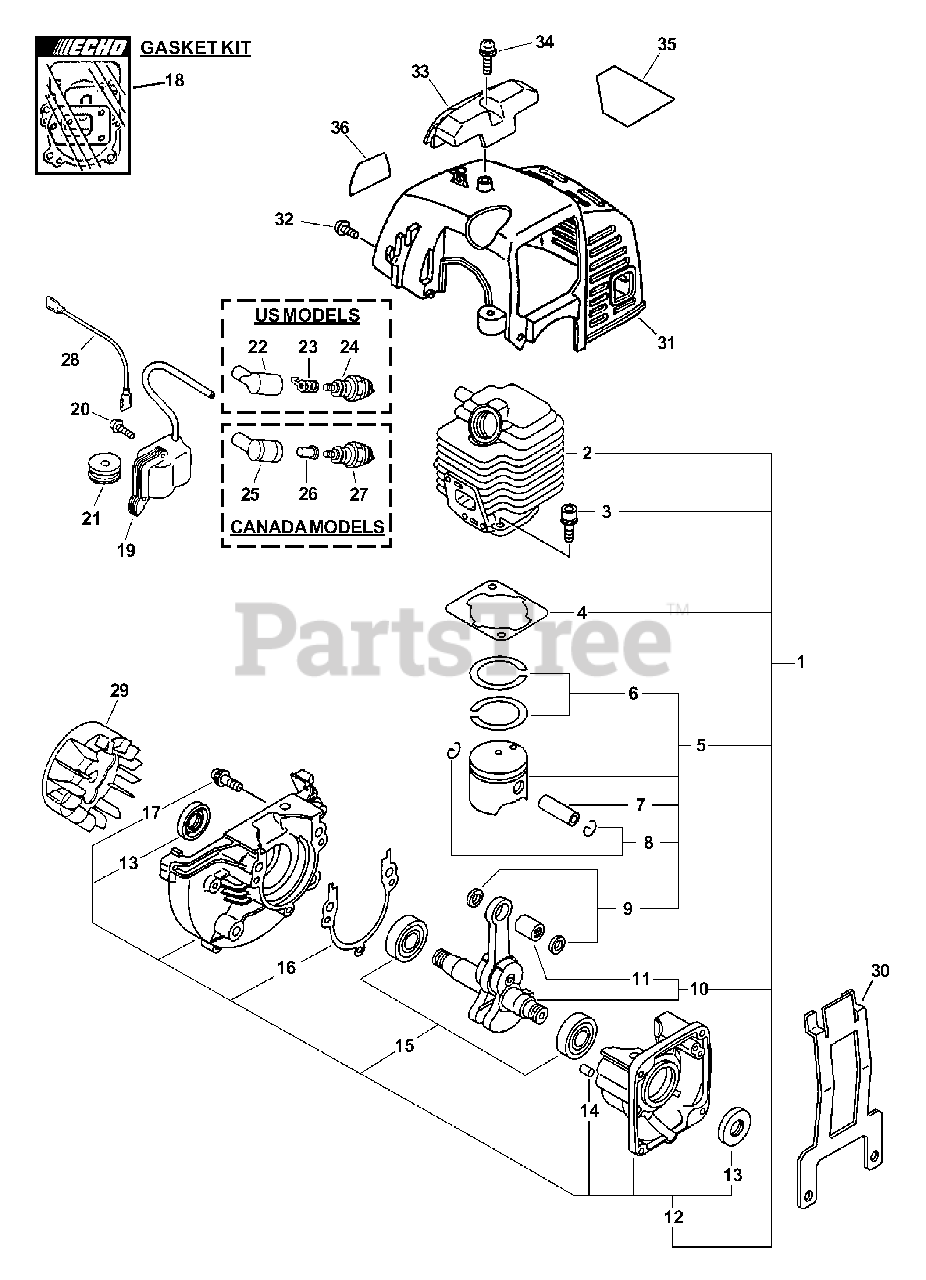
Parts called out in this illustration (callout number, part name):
1	SHORT BLOCK ES-2100;PB-2100
2	CYLINDER
3	BOLT 5×22
4	GASKET, CYLINDER
5	PISTON KIT
6	RING, PISTON
7	PIN, PISTON 8
8	RING, SNAP
9	WASHER, THRUST
10	CRANKSHAFT ASSY
11	BEARING, NEEDLE
12	CRANKCASE KIT
13	SEAL, OIL 12
14	PIN, LOCATING 4
15	BEARING, BALL - 6201 C3
16	GASKET, CRANKCASE
17	BOLT 5×28
18	GASKET KIT
19	COIL, IGNITION
20	SCREW 4×22
22	CAP, SPARK PLUG
23	TERMINAL, SPARK PLUG
24	SPARK PLUG - BPM7A
25	CAP, SPARK PLUG
26	ADAPTOR, SPARK PLUG - CAP
27	SPARK PLUG - BPMR7A
28	LEAD
29	FLYWHEEL
30	GUARD, ENGINE
31	COVER, ENGINE - ORANGE
32	SCREW 4×12
33	GUARD, TOP - BLACK
34	SCREW 5×16
35	LABEL, CAUTION
36	LABEL, MODEL
